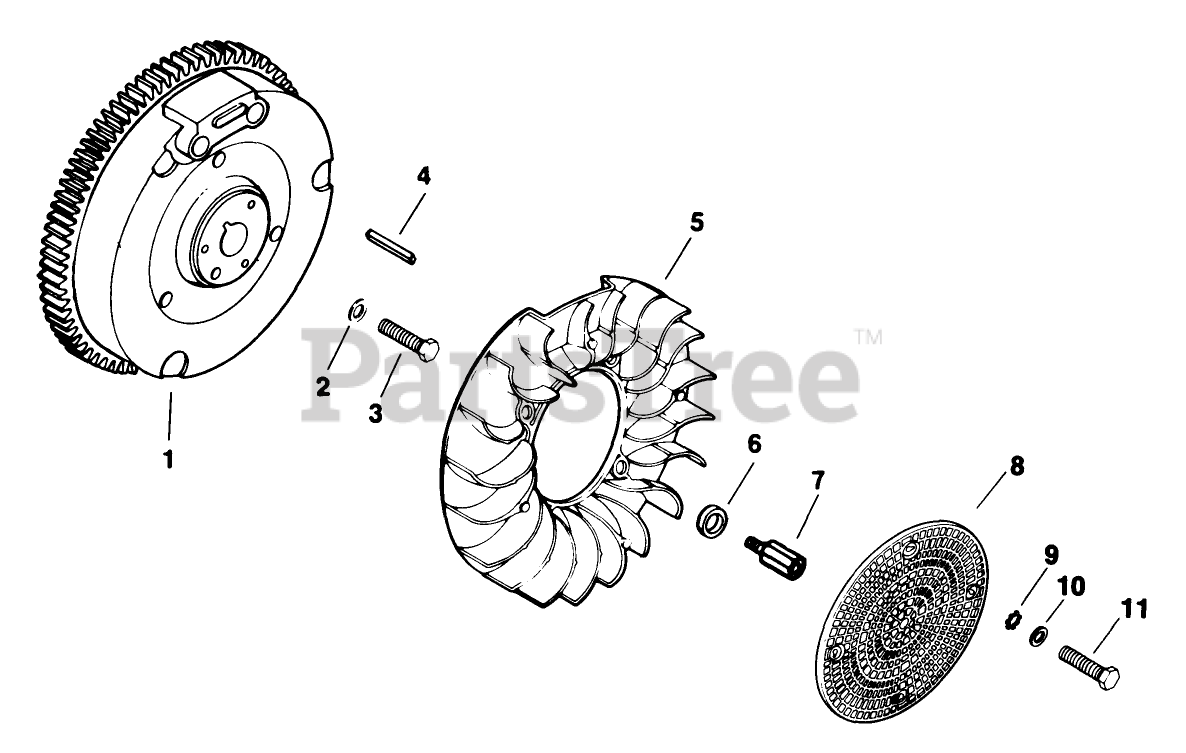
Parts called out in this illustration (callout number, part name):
1	Flywheel
2	Washer-Flat
3	Screw-H.C.
8	Screen-Grass
9	Washer-Lock
10	Washer
11	Screw-T.H.
